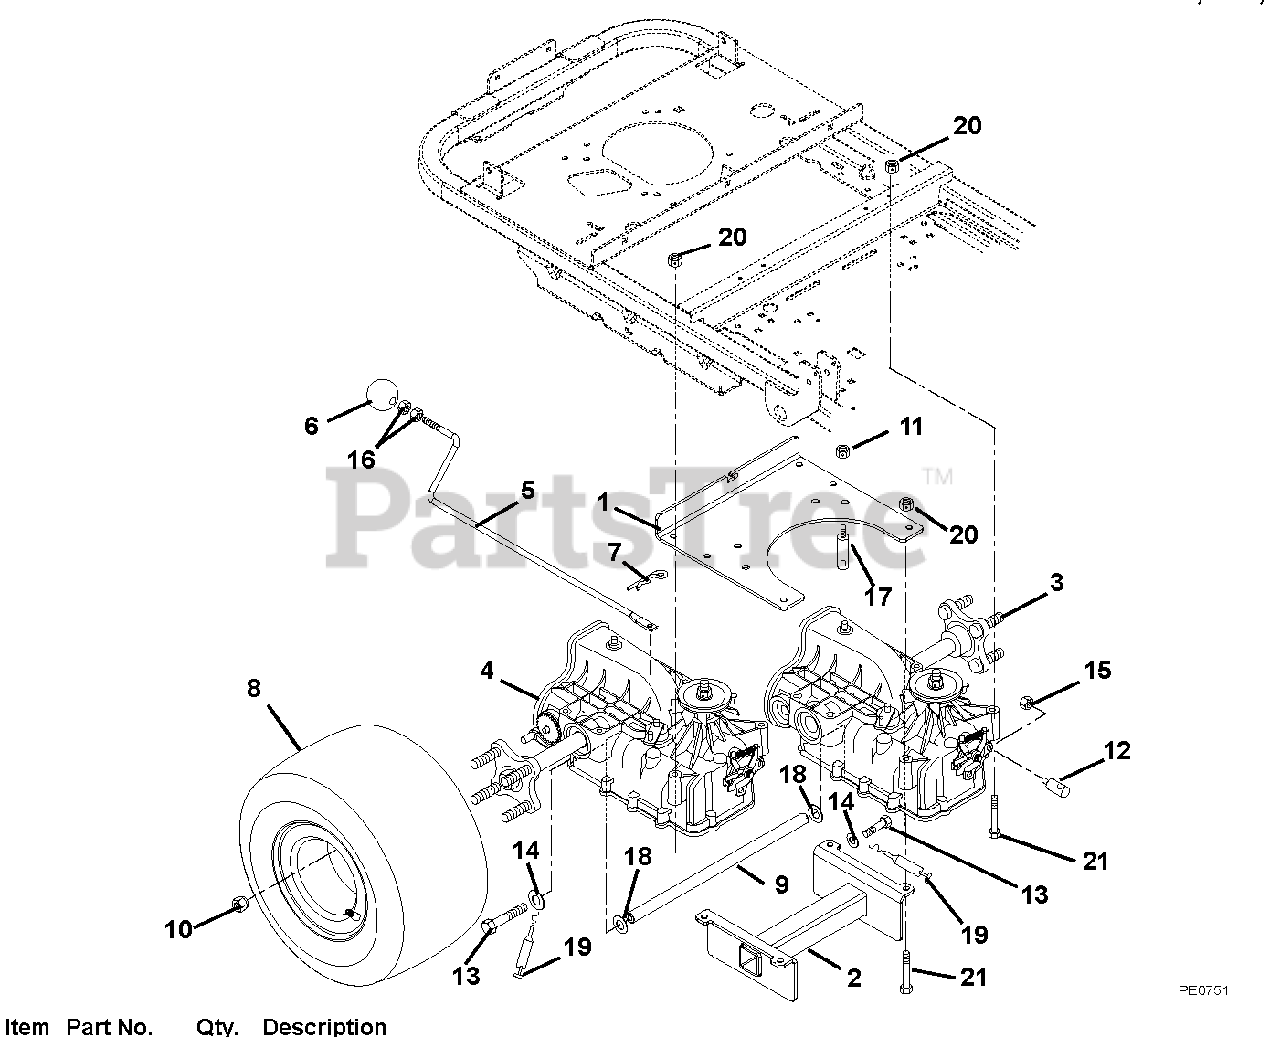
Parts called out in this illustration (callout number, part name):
1	Bracket, Transmission Axle Support
2	Weldment, Transmission Axle Brace
3	Transaxle, Left Hand
4	Transaxle, Right Hand
5	Rod, Dump IZT
7	Pin, Hair
8	Assembly, Tire 9.5 x 18-2 Ply (401, 402)
9	Rod, Axle Brace
10	Nut, Lug .50-20
11	Nut, .38-16 Flange Nyloc
12	Rod Pivot
13	Bolt, Hex .31-18 x 2.50 Grade 5
14	Washer, Locking .31 x .078 Regular
15	Nut .312-18 Flange Nyloc
16	Nut, Jam .312-18
17	Shoulder Stud
18	Washer, Flat Steel .38 x .87 x .179
19	Adhesive Sealant
20	Nut-.31-18 Flange Nyloc
21	Bolt-Hex .31-18 x 2.75 Grade 5
